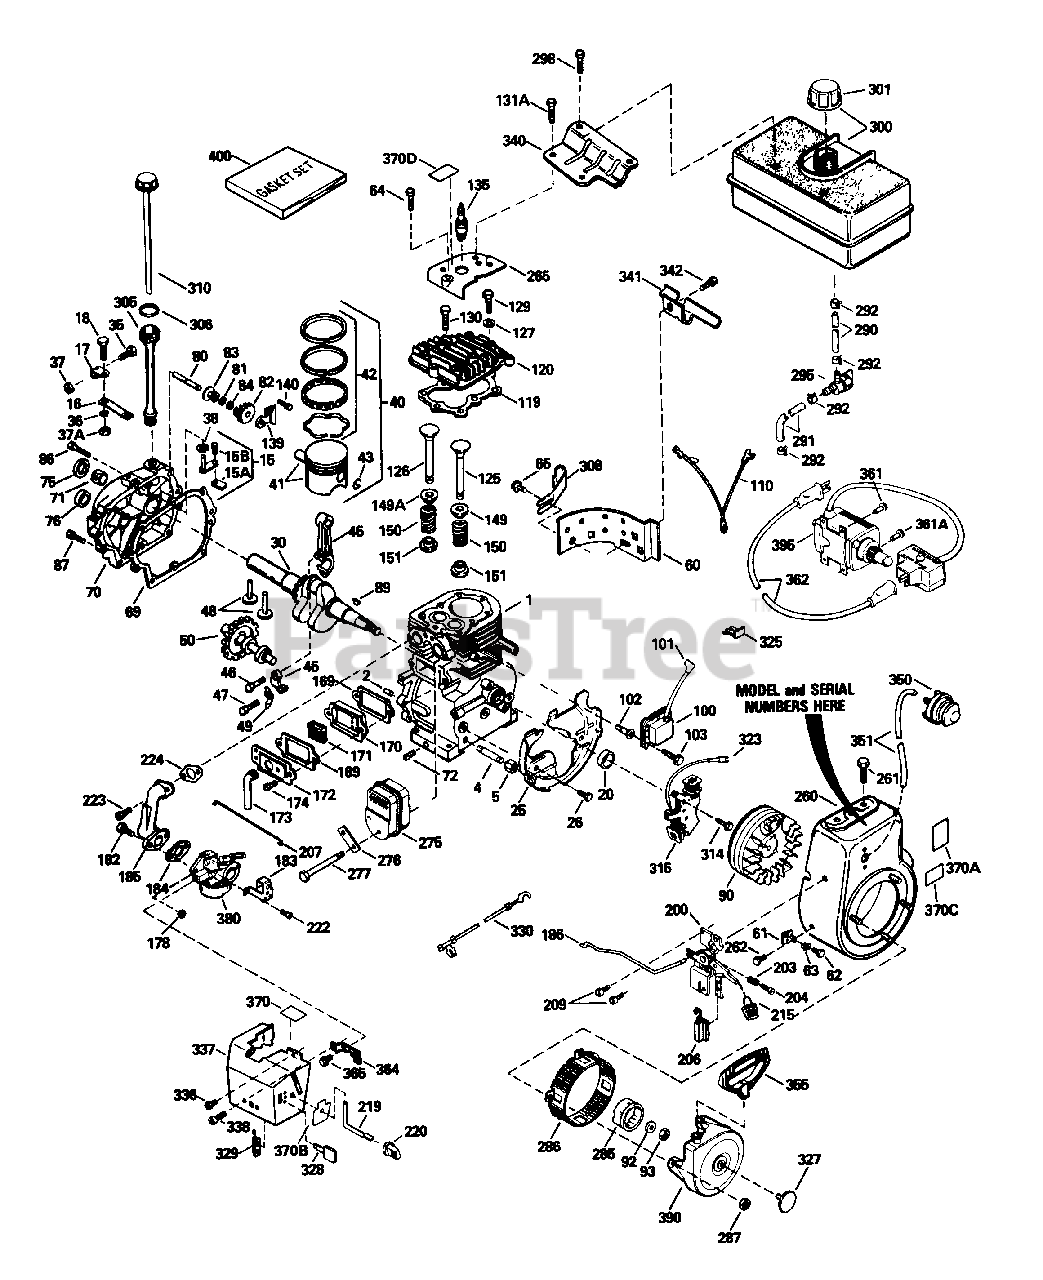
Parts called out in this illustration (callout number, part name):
1	Cylinder
2	Pin, Dowel
4	Nipple, Pipe, 5-1/2"
5	Cap, Oil Drain
15	Rod Ass'y., Governor
15A	Yoke, Governor
15B	Screw, Fil. Hd. Sems, 6-40 x 5/16
16	Lever, Governor
17	Clamp, Governor Lever
18	Screw, Hex Washer Hd., 8-32 x 5/16
20	Seal, Oil
25	Baffle, Blower Housing
26	Screw, Hex Washer Hd. Durlok, 1/4-20 x 5/8
30	Crankshaft
35	Screw, Hex Washer Hd., 10-32 x 3/4
36	Washer, E.T. Lock No. 8
37	Nut & Lock Washer, 10-32 "Keps"
37A	Lock Nut, Hex "Keps," 8-32
38	Ring, Retaining
40	Piston, Pin & Ring Ass'y. (Std.)
40	Piston, Pin & Ring Ass'y. (.010 Oversize)
40	Piston, Pin & Ring Ass'y. (.020 Oversize)
41	Piston & Pin Ass'y. (Std.)
41	Piston & Pin Ass'y. (.010 Oversize)
41	Piston & Pin Ass'y. (.020 Oversize)
42	Ring Set, Piston (Std.)
42	Ring Set, Piston (.010 Oversize)
42	Ring Set, Piston (.020 Oversize)
43	Ring, Piston Pin Retaining
45	Rod Ass'y., Connecting
46	Bolt, Connecting Rod
47	Bolt, Connecting Rod
48	Lifter, Valve
49	Dipper, Oil
50	Camshaft (Mechanical Compression Release)
60	Extension, Blower Housing
61	Bracket, Grommet Mounting
62	Screw, Pan Hd. Taptite, 8-32 x 3/8
63	Grommet, Plastic
64	Screw, Hex Washer Hd. Taptite, 1/4-20 x 5/8
65	Screw, Hex Hd. Sems, 10-24 x 1/2
69	Gasket, Cylinder Cover
70	Cover Ass'y., Cylinder
71	Bushing, Cylinder Cover
72	Plug, Pipe
75	Seal, Oil
76	Seal, Oil (Camshaft)
80	Shaft, Governor
81	Washer, Flat
82	Gear, Governor
83	Spool, Governor
84	Ring, Retaining
86	Screw, Hex Washer Hd. Powerlok, 1/4-20 x 1-3/16
87	Screw, Hex Washer Hd. Powerlok, 1/4-20 x 1-11/16
89	Key, Flywheel
90	Flywheel (w/Ring Gear)
92	Washer, Lock
93	Nut, Flywheel
100	Solid State Ass'y.
101	Cover, Spark Plug
102	Stud, Solid State Mounting
103	Screw, T-15 Torx Hex Washer Hd. Sems, 10-24 x 1
110	Wire, Ground
119	Gasket, Cylinder Head
120	Head, Cylinder
125	Valve, Exhaust (Std.)
125	Valve, Exhaust (1/32" Oversize)
126	Valve, Intake (Std.)
126	Valve, Intake (1/32" Oversize)
127	Washer, Flat
129	Screw, Special Hex Hd. Tapped, 5/16-18 x 1-3/4
130	Screw, Hex Flange Hd., 5/16-18 x 1-1/2
131A	Screw, Hex Hd., 5/16-18 x 5/8
135	Spark Plug
139	Bracket, Governor Gear
140	Screw, Hex Washer Hd. Thread Forming, 10-24 x 1/2
149	Cap, Upper Valve Spring
149A	Seal Ass'y., Intake Valve
150	Spring, Valve
151	Cap, Lower Valve Spring
169	Gasket, Breather
170	Body, Breather
171	Element, Breather
172	Cover, Breather
173	Tube, Breather
174	Screw, Hex Hd. Sems, 10-24 x 1/2
178	Nut & Lock Washer, 1/4-28
182	Screw, Fil. Hd. Sems, 1/4-28 x 1
183	Bracket, Choke
184	Gasket, Carburetor
185	Pipe, Intake
186	Link, Governor
200	Bracket Ass'y., Control
203	Spring, Compression
204	Screw, Fil. Hd., 5-40 x 7/16
207	Link, Governor-To-Throttle
209	Screw, Hex Washer Hd. Thread Cutting, 10-32 x 1/2
215	Knob, Control
219	Rod, Choke
220	Knob, Choke
222	Screw, Fil. Hd. Sems, 10-32 x 1/2
223	Screw, T-30 Torx Fil. Hd. Sems, 5/16-18 x 1-1/8
224	Gasket, Intake Pipe
260	Housing, Blower
261	Screw, Hex Hd. Spinlock Thread Forming, 5/16-18 x 3/4
262	Screw, Hex Hd. Sems, 5/16-24 x 21/32
265	Cover, Cylinder Head
276	Plate, Lock
277	Screw, Flanged Hex Hd., 5/16-18 x 4-3/16
285	Hub, Starter
286	Screen, Starter
287	Nut & Lock Washer, 1/4-28
290	Line, Fuel
291	Line, Fuel
292	Clamp, Fuel Line
295	Valve, Fuel Shut-Off
298	Screw, Hex Washer Hd. Thread Cutting, 1/4-15 x 7/8
300	Tank, Fuel
301	Cap, Fuel Tank
305	Tube, Oil Fill
308	Clip, Fill Tube
310	Dipstick, Oil
314	Screw, Hex Hd. Sems, 1/4-20 x 3/4
315	Coil Ass'y., Alternator (18 Watt)
325	Clip, Wire
327	Plug, Starter
328	Ignition, Key
330	Wire, Ground
336	Screw, Hex Washer Hd. Self-Drilling, 10-32 x 1/2
337	Cover, Carburetor
338	Screw, Hex Washer Hd. Sems, 10-32 x 3/8
340	Bracket, Fuel Tank
341	Plate, Fuel Tank Mounting
342	Screw, Hex Washer Hd. Durlok, 1/4-20 x 5/8
350	Primer Ass'y.
351	Line, Primer
355	Starter Handle, Mitten Grip
361	Screw, Hex Hd. Shoulder, 1/4-20 x 1/2
361A	Screw, Torx T-30 Hex Washer Hd. Sems, 1/4-20 x 1/2
362	Cord, Extension
364	Bracket, Carburetor Cover Mounting
365	Screw, Hex Washer Hd. Sems, Taptite, 8-32 x 27/64
370	Decal, Warning (Bilingual)
370A	Decal, Name
370B	Decal, Control
370C	Decal, Primer
370D	Decal, Instruction
380	Carburetor
390	Starter, Rewind
395	Motor Kit, Electric Starter (120 Volt)
400	Gasket Kit
